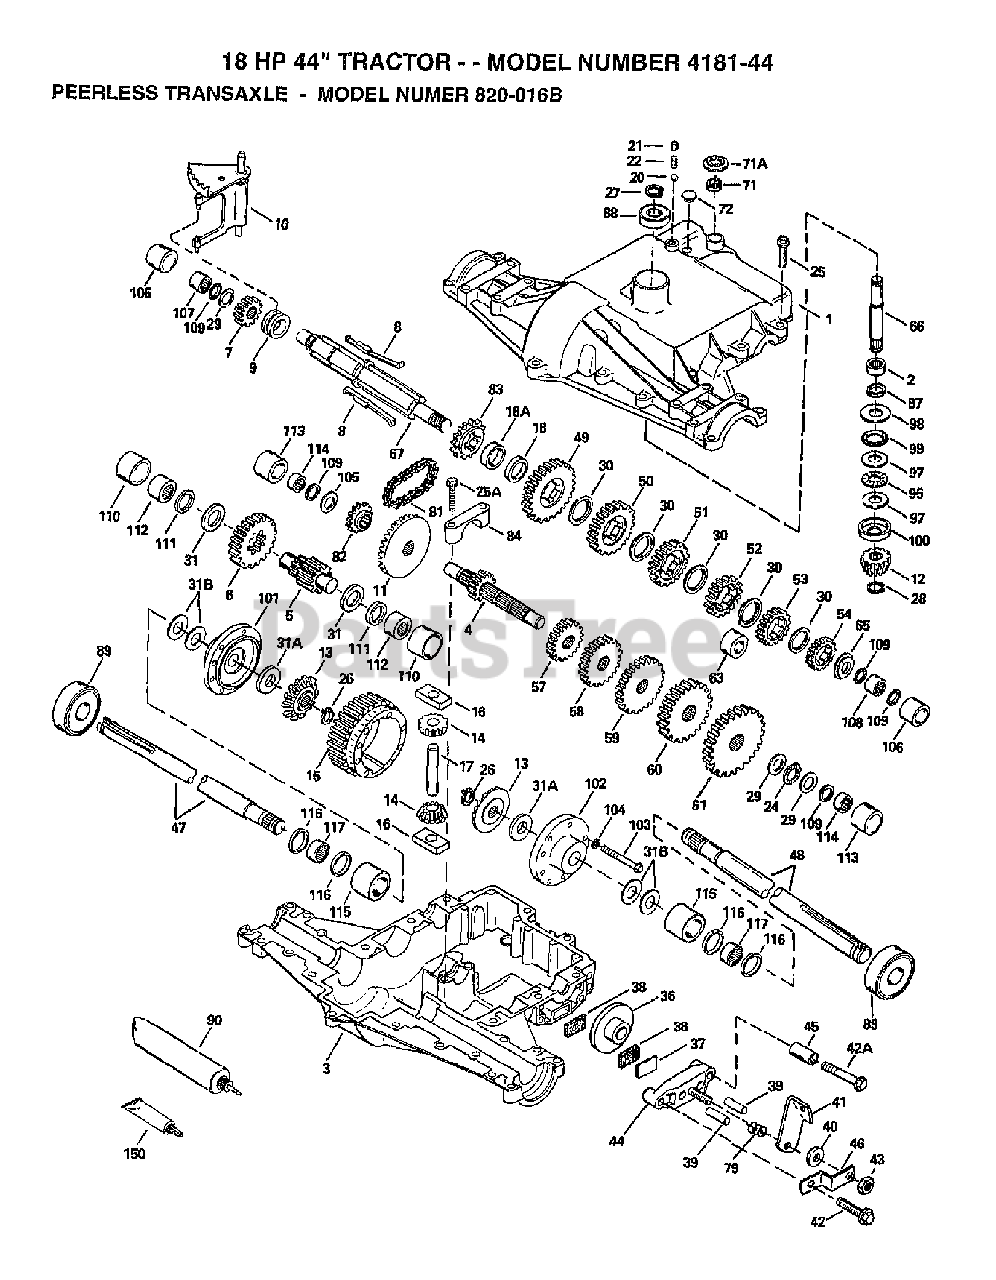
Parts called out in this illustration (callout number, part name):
1	Poulan TBD
49	Poulan TBD
50	Poulan TBD
51	Poulan TBD
53	Poulan TBD
90	Poulan TBD
114	Oil Seal
